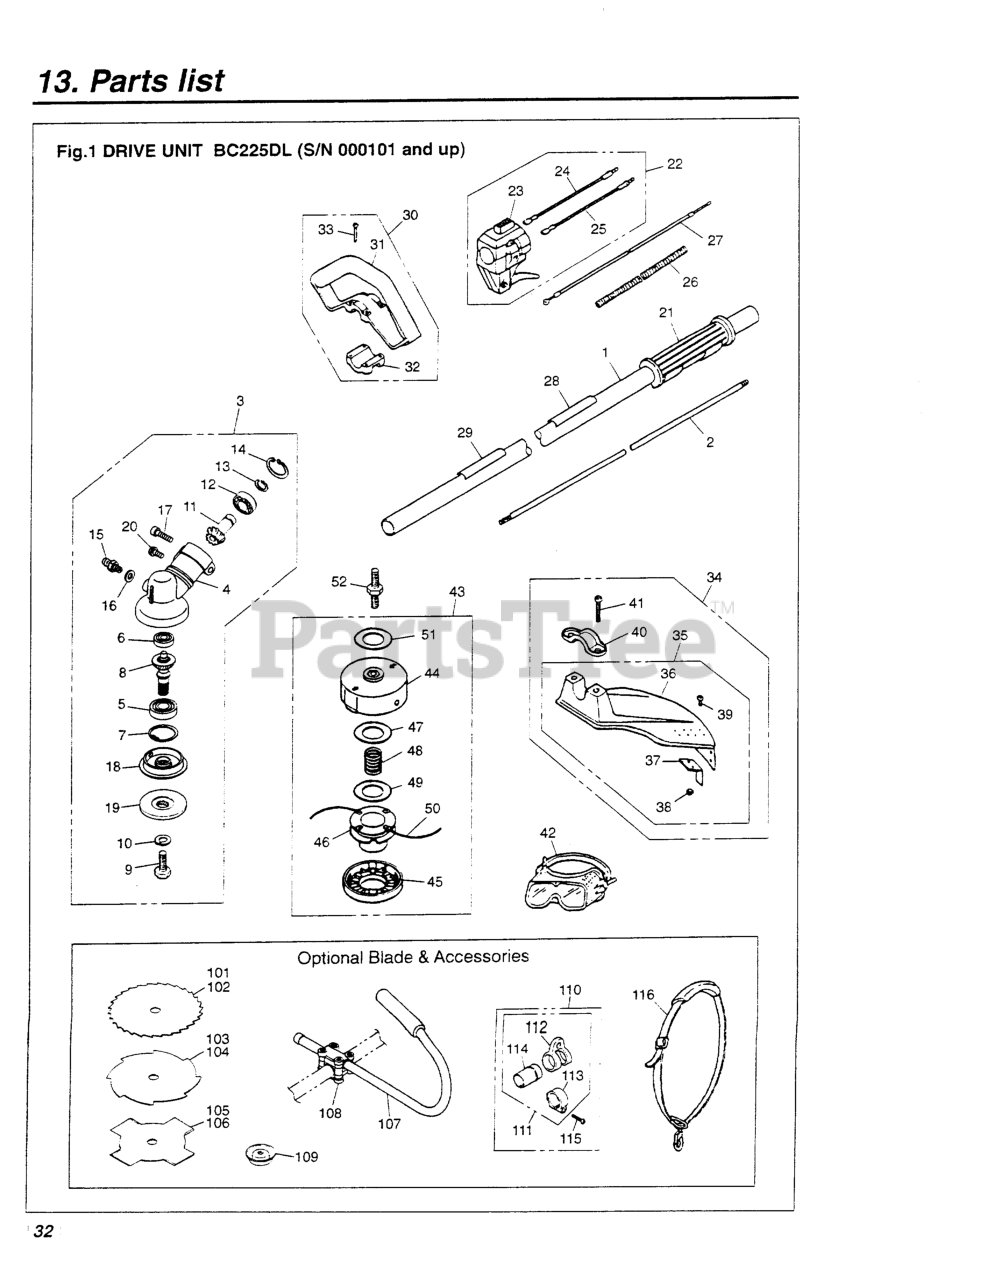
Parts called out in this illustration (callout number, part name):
1	PIPE COMP
2	SHAFT, DRIVE
3	GEARCASE
4	GEARCASE
5	BEARING
6	BEARING
7	RING, SNAP, M26 X 1.2
8	SHAFT COMPLETE
9	BOLT
10	WASHER
11	PINION
14	RING, SNAP, M24 x 1.2
15	FITTING, GREASE
16	WASHER, M6 X .8
17	BOLT, M5 X 20
18	HOLDER (A)
19	HOLDER (B)
20	BOLT, M5 X 10
21	GRIP (RPLS 3577-32140 & 3220-
24	CORD (A), BLACK
25	CORD (B), RED
26	TUBE
27	CABLE COMP (RPLS 1633-83100)
28	PLATE, NAME (BC225DL)
29	PLATE, CAUTION
30	HANDLE ASSEMBLY
31	HANDLE
33	SCREW, M5 x 35
34	GUARD ASSY (RPLS 6041-24110)
37	BLADE
38	NUT
39	SCREW, M5 x 12
40	CLAMP (REPLACES 5807-24120)
41	BOLT, M6 x 1.30
42	GOGGLE
43	4
44	CASE (RPLS -15112)
45	COVER (RPLS -15130)
46	HOLDER, CORD (RPLS -15141)
47	PLATE, LARGE
48	SPRING (RPLS -99161)
49	PLATE, SMALL
50	CORD
51	SPACER
52	SHAFT
101	BLADE, 9
102	BLADE, 9
103	BLADE, 8
104	BLADE, 9
105	BLADE, 8
106	BLADE, 9
107	HANDLE, J
108	BRACKET ASSY (REPLACES -14100)
109	COVER (RPLS 6460-13280)
110	HANGER ASSEMBLY
111	HANGER COMPLETE
112	HANGER
113	CLAMP
114	SLEEVE
115	SCREW, M5 x 25
